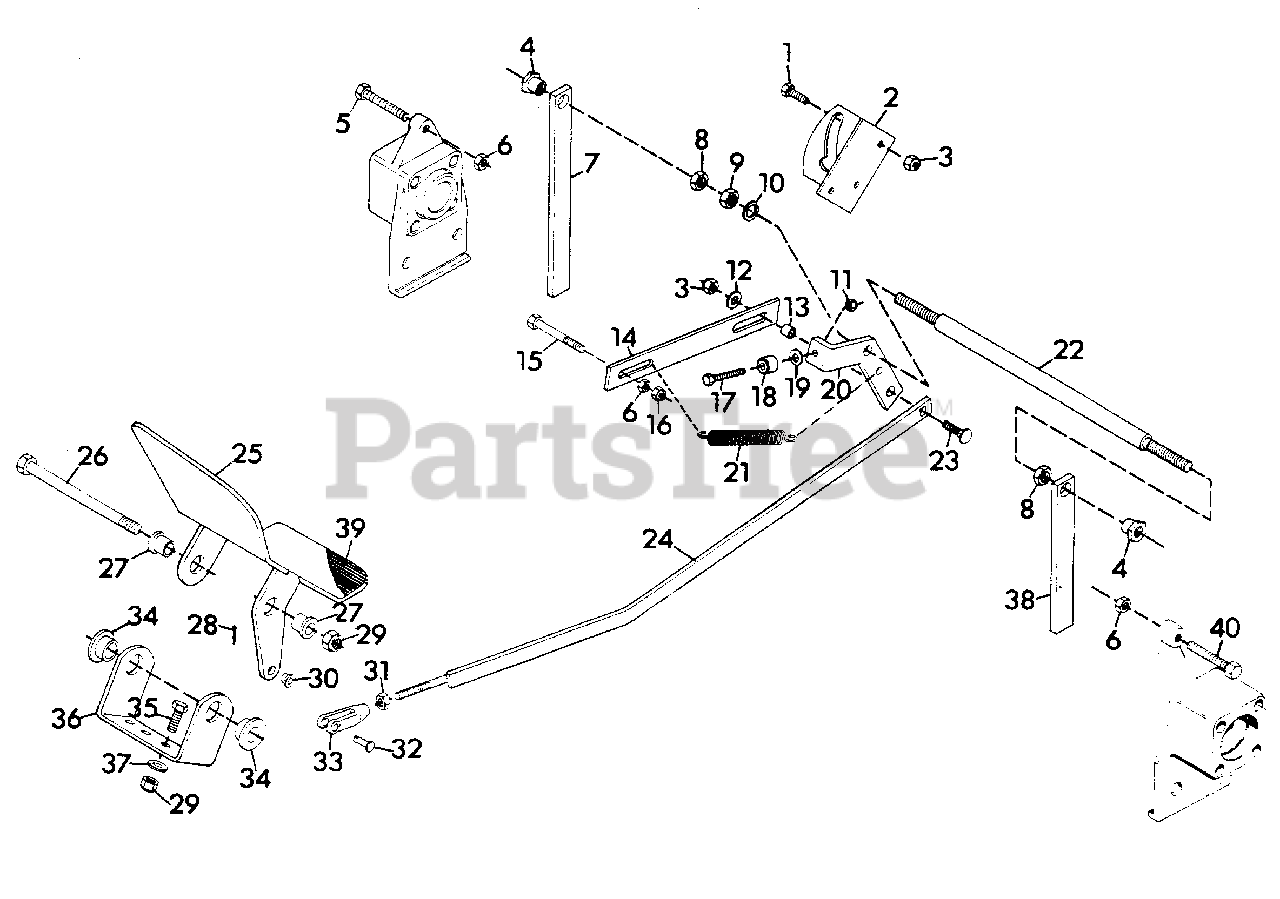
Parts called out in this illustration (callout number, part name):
1	BOLT, HEX 5/16-18X1.00
2	WELDMENT, FWD-REV ACTUATING
3	NUT, LOCK 5/16-18
4	BUSHING, FWD-REV SLIDE ROD
5	BOLT, HEX 3/8-16X2.00 SPECIAL
6	NUT, HEX 3/8-16
7	SPRING, FWD-REV CLUTCH
8	NUT, JAM 1/2-13 HEX
9	NUT, HEX 1/2-13
10	WASHER, LOCK 1/2 SP HEAVY
11	NUT, LOCK 1/4-28
12	WASHER, FLAT .313X.875X.065
13	BUSHING, FWD-REV LINKAGE
14	STRAP, NEUTRAL DETENT
15	BOLT, HEX 3/8-16X3.00
16	NUT, LOCK 3/8-16
17	BOLT, HEX 1/4-28X1.38 GR. 8
18	ROLLER, CLUTCH CAM
19	WASHER, FLAT .281X.625X.065
20	ARM, FWD-REV CLUTCH ROLL
21	SPRING, NEUTRAL DETENT
22	ROD, FWD-REV SLIDE
23	BOLT, 5/16-18X1.25 RD HD SQ NK
24	WELDMENT, FWD-REV SHIFTER
25	PEDAL, FOOT CLUTCH
26	BOLT, HEX 1/2-13X6.50
27	BUSHING, .513X.750X.625
28	PIN, COTTER .09X.75
29	NUT, LOCK 1/2-13
30	BUSHING, NYLON .32X.437X.248
31	NUT, HEX 5/16-24
32	PIN, CLEVIS 5/16X.812
33	YOKE
34	BUSHING, NYLON .76X1.00X.76 FLG.
35	BOLT, HEX 1/2-13X1.25
36	BRACKET, CLUTCH PEDAL PIVOT
37	WASHER, FLAT .531X1.250X.100
38	SPRING, REVERSE CLUTCH
39	PAD
40	BOLT, HEX 3/8-16X2.50
